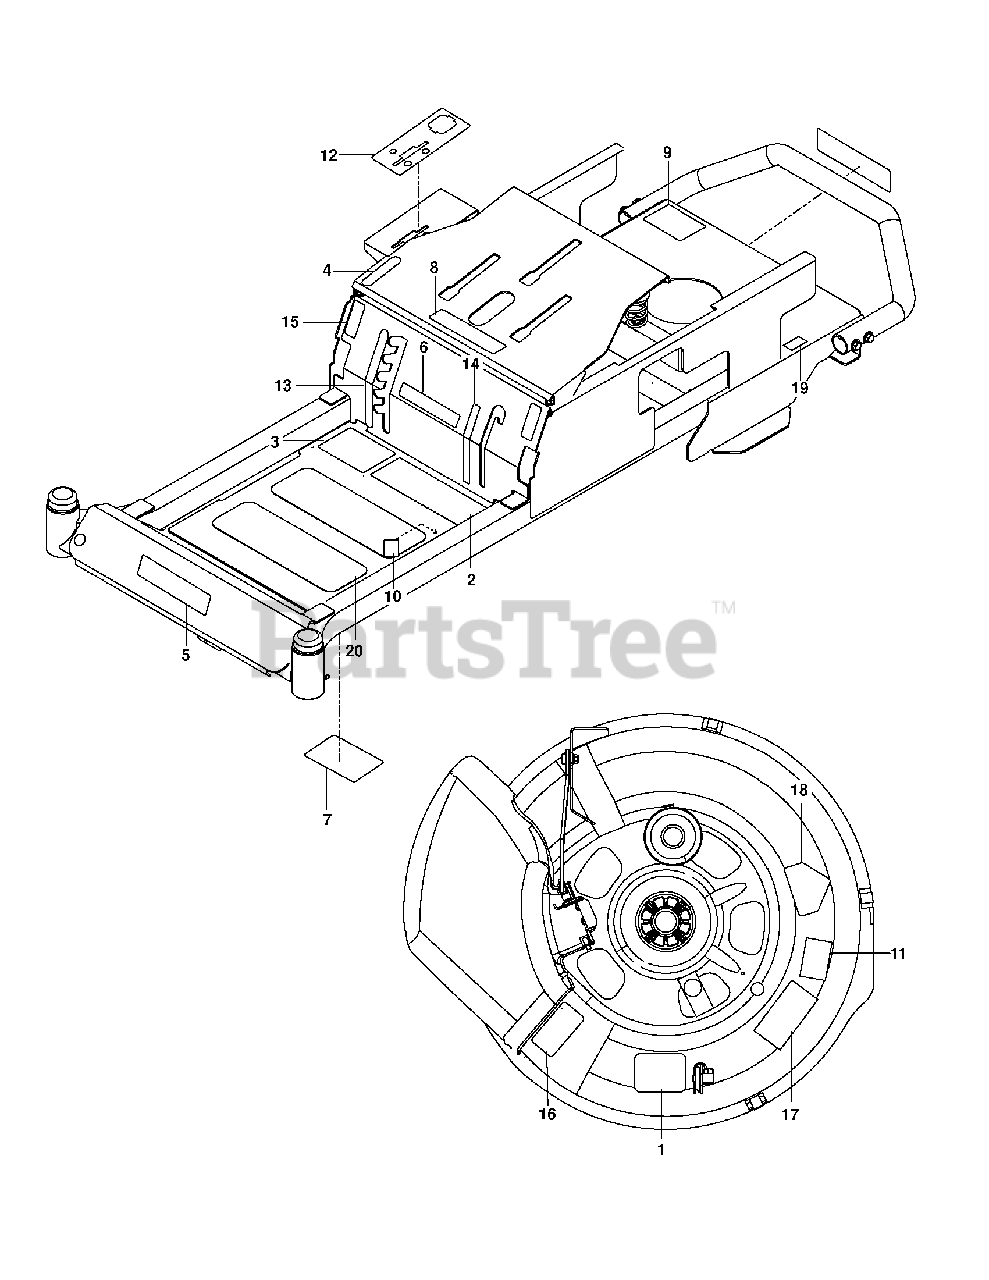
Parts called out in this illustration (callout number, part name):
1	DECAL, BELT ROUTING
2	DECAL, SAFETY WARNING
3	DECAL, WARNING
4	DECAL, PARK BRAKE
6	DECAL, SPEEDZTR 6.5"
7	DECAL, SERVICE
9	DECAL, DO NOT MOUNT
11	DECAL, 30, WHITE
12	DECAL, CONTROL PANEL
13	DECAL, DECK HEIGHT
14	DECAL, BLADE ENGAGEMENT
15	DECAL, MOTION CONTROL
17	DECAL, EURO SEVERING
18	DECAL, CPSC
19	DECAL, ECM, AUSTRALIA
20	ANTI-SKID PAD
